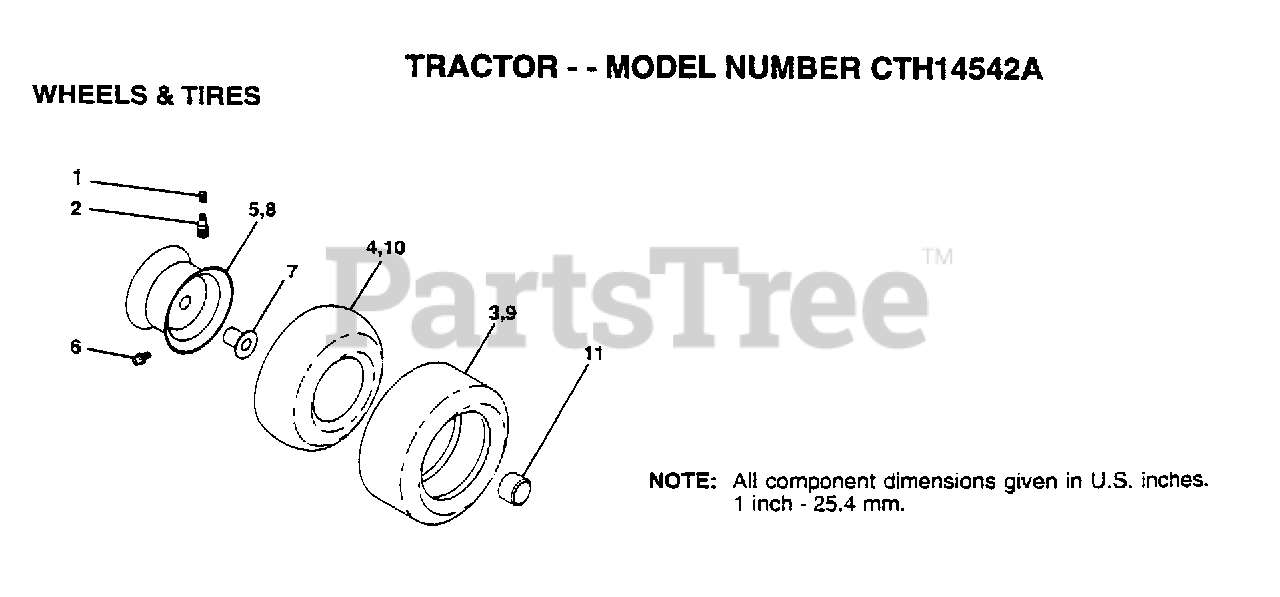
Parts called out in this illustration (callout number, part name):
1	VALVE CAP
2	VALVE STEM LT
4	TUBE.5.3/4.5/6
5	"RIM.ASM.6""FRONT"
6	FITTING LT
7	"FLANGE, BEARING"
8	"RIM.ASM.8""REAR"
10	TUBE.18X9.5-8
11	HUB CAP
